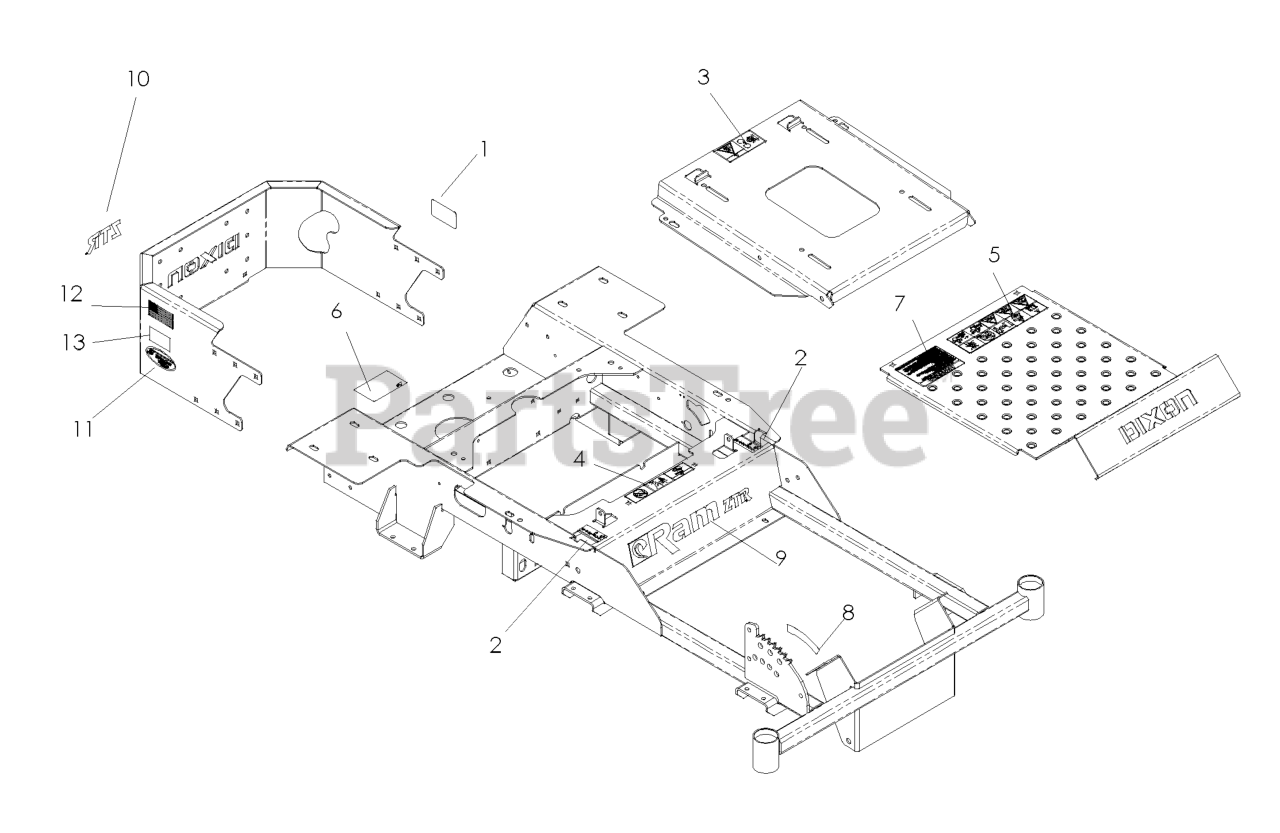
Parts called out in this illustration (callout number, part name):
1	DECAL, PROP. 65
2	DECAL, MOTION CONTROL
3	DECAL, BELT DRIVE
4	DECAL, BATTERY
5	DECAL, WARNING
6	DECAL, DO NOT MOUNT
7	DECAL, WARNING
8	DECAL, HEIGHT
9	DECAL, RAM
10	DECAL, ZTR
11	HG DECAL(BLN-52241)
12	DECAL, FLAG
